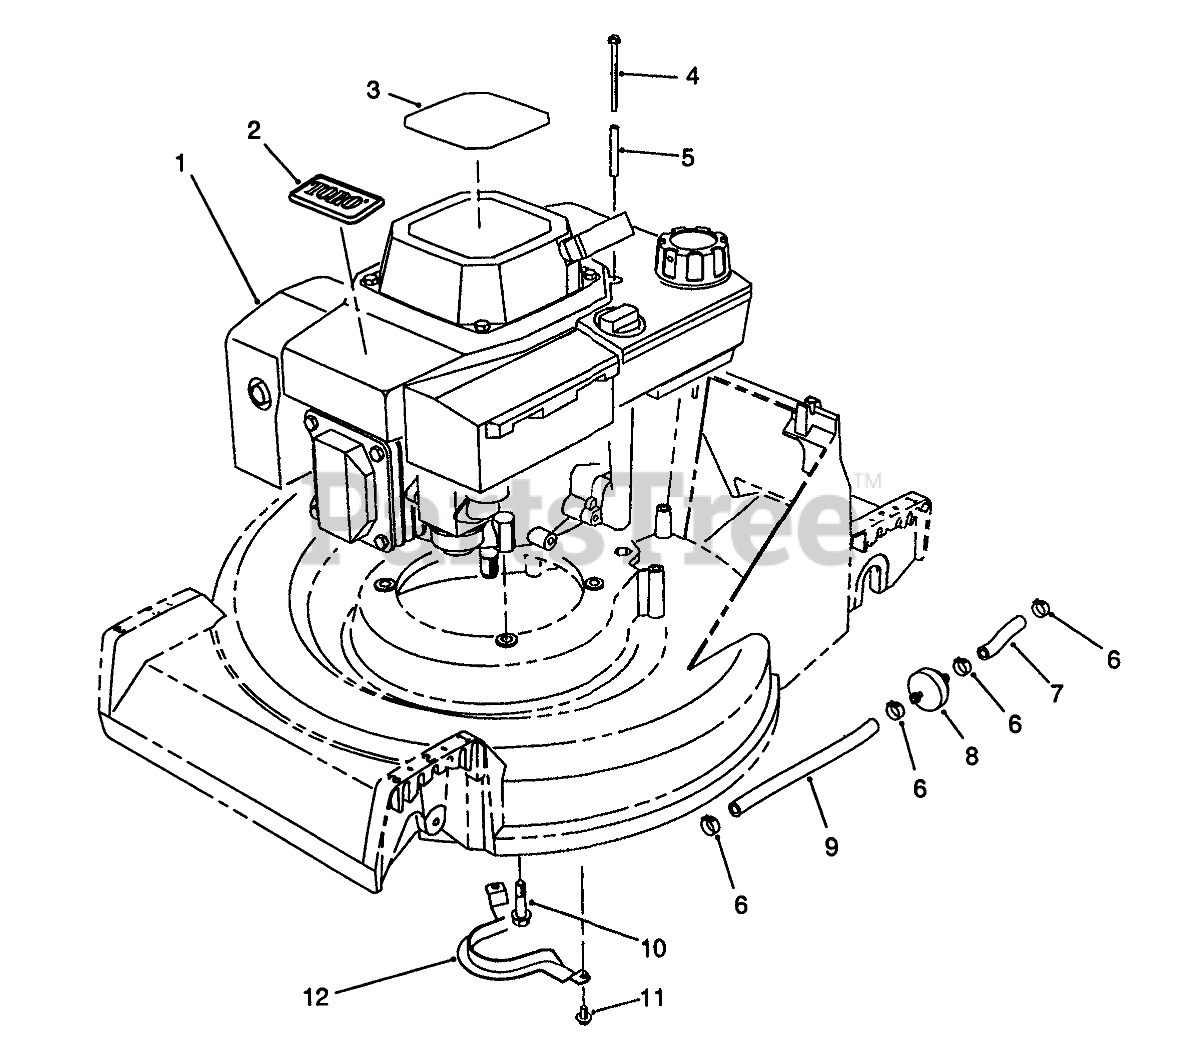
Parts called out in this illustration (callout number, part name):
1	ENGINE ASSY BBC OHV SU
2	TORO LOGO PLT
3	DECAL - OHV RECOIL
4	THRD FORMING SCREW
5	TUBULAR SPACER
6	CLAMP-FUEL LINE
7	LINE-GAS
8	FILTER-FUEL
9	HOSE-FUEL
10	SCREW-HWHTF
11	SCREW-HWHTF
12	Guide-Belt
